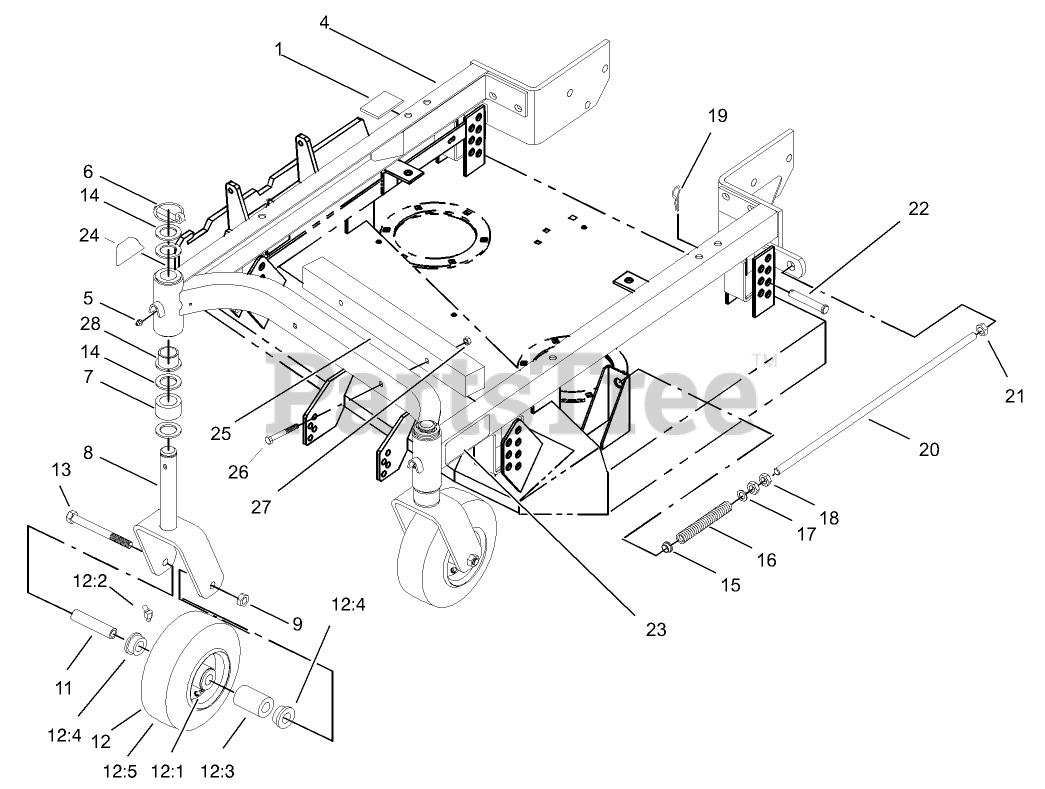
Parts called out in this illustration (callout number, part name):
1	CUSHION-RUBBER
4	36" Carrier Frame
5	FITTING-GREASE
7	SPACER-CASTOR
8	CASTOR FORK ASM
9	NUT-HEX
11	BUSHING-SPANNER
12	CASTER WHEEL ASM
12:1	STEM-VALVE
12:2	FITTING-LUBE, 45 DEG
12:3	BEARING
12:4	BEARING-OUTSIDE
12:5	TIRE-TUBELESS
13	SCREW-HH
14	WASHER-THRUST
15	BUSHING-FLANGE
16	SPRING
17	WASHER
18	NUT-JAM
19	PIN-HAIR
20	SHAFT-ADJUSTING
21	NUT-LOCK, NI
22	PIN-CLEVIS
23	DECAL-HOC, LH
24	DECAL-HOC, RH
25	Front Weight
26	SCREW-HH
27	NUT-LOCK, NI
28	BUSHING
